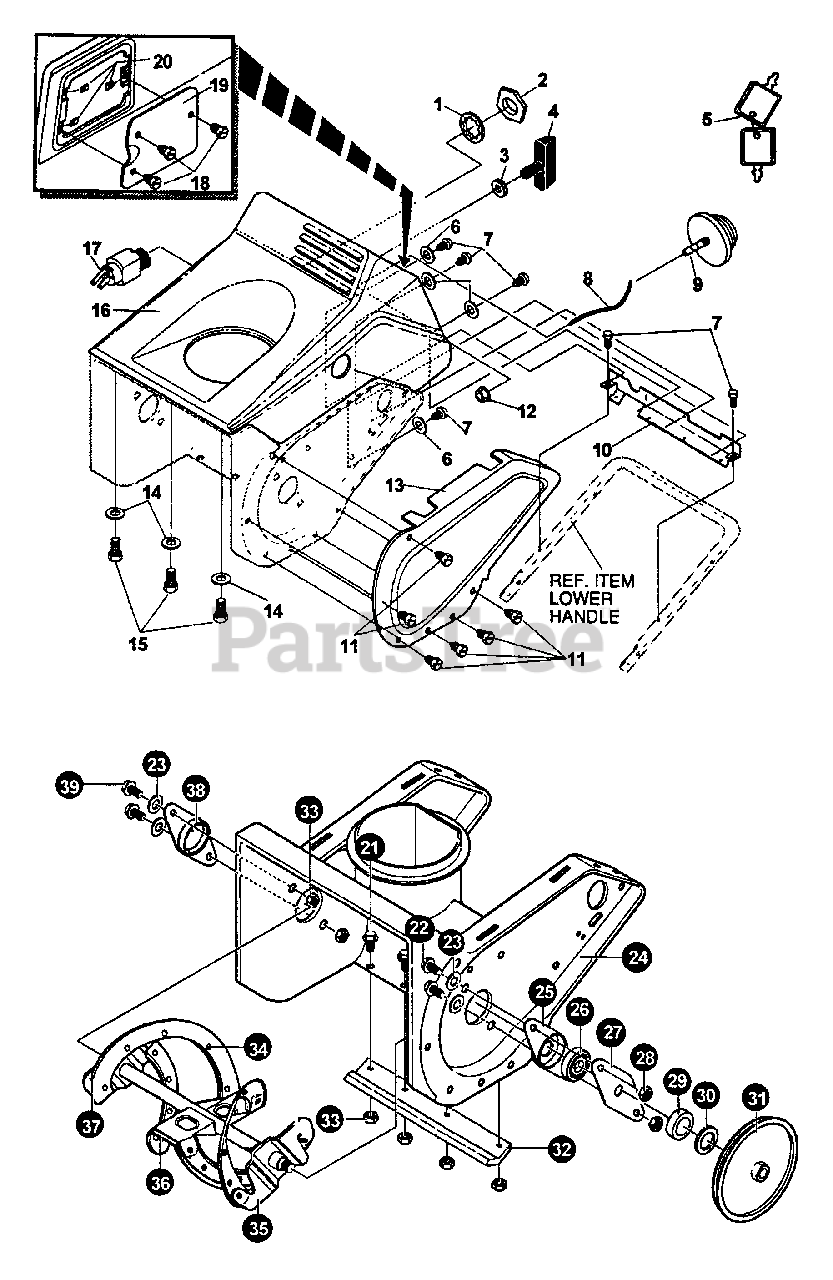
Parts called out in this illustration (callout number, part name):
1	WASHER
2	NUT
3	GUIDE, ROPE
4	KNOB, TEE
5	KEYS & RING ASSY
6	WASHER
7	SCREW - 10-24×0.63" -- PAN HEAD
9	PRIMER, ENGINE 2CY
10	BRACKET
11	SCREW 10-24×38
12	NUT
13	COVER, BELT
14	WASHER
15	SCREW
16	COVER
17	SWITCH, IGNITION
19	DOOR, ACCESS
20	NUT
21	SCREW 1/4"-20×0.63
22	SCREW 1/4 - 20×75 HHC
23	WASHER
24	AUGER INTAKE ASSY - 21"
25	RETAINER, BEARING
26	BEARING, BALL
27	RETAINER, BEARING
28	NUT, 1/4"-20
29	SPACER, SLEEVE 0.640×0.88×0.15
30	WASHER, FLAT
31	PULLEY
32	BLADE, SCRAPER
33	NUT, 1/4"-20
34	RIVET, 0.250×.5 IN.
35	AUGER ASSY - 21"
36	AUGER, CENTER BLADE STRIP
37	AUGER, BLADE STRIP
38	BEARING, FLANGE
39	SCREW 1/4"-20×0.88
